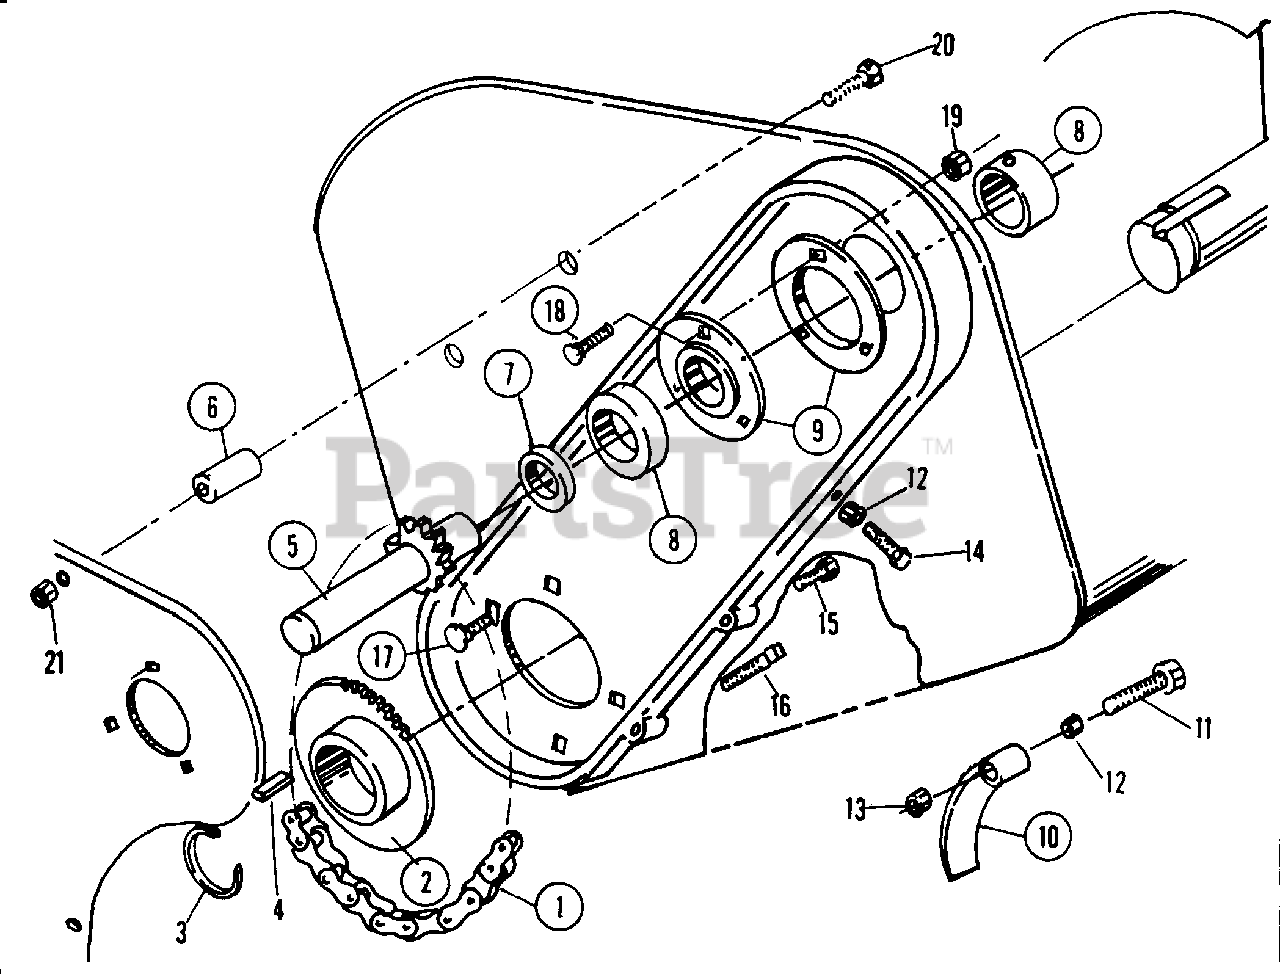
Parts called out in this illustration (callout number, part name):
1	CHAIN, ENCLOSED DRIVE
2	SPROCKET & HUB, DRIVEN
3	RING, RETAINING 1.387 x .052
4	KEY, Square 3/8 x 1
5	SPROCKET & SHAFT
6	TUBE, SUPPORT
7	SPACER, UPPER SHAFT 1.05" DI x 1.312" OD x .41"
8	BEARING, SEALED (Fafnir RA00NPPB)
9	FLANGETTE, 3-HOLE
10	PADDLE, CHAIN TIGHTENER
11	HHCS, 5/16C X2-3/4
12	NUT, 5/16-18 HEX
13	LOCKNUT, 5/16-18 HEX
14	SETSCREW, HEX SOCKET HEAD 5/16-18x1.5 (Use 7091590)
15	BOLT, Carriage 3/8-16X2-3/4 GR5 YZ
16	BOLT, Carriage Special 3/8-16 x 2-3/4 (Make from 7092000)
17	BOLT, Carriage 1/2-13X1-1/2
18	BOLT, Carriage 5/16C X3/4 GR5 ZP
19	LOCKNUT, 5/16-18 HEX
20	HHCS, 1/2C X3 GR5 ZP
21	LOCKNUT, 1/2-13 HEX
